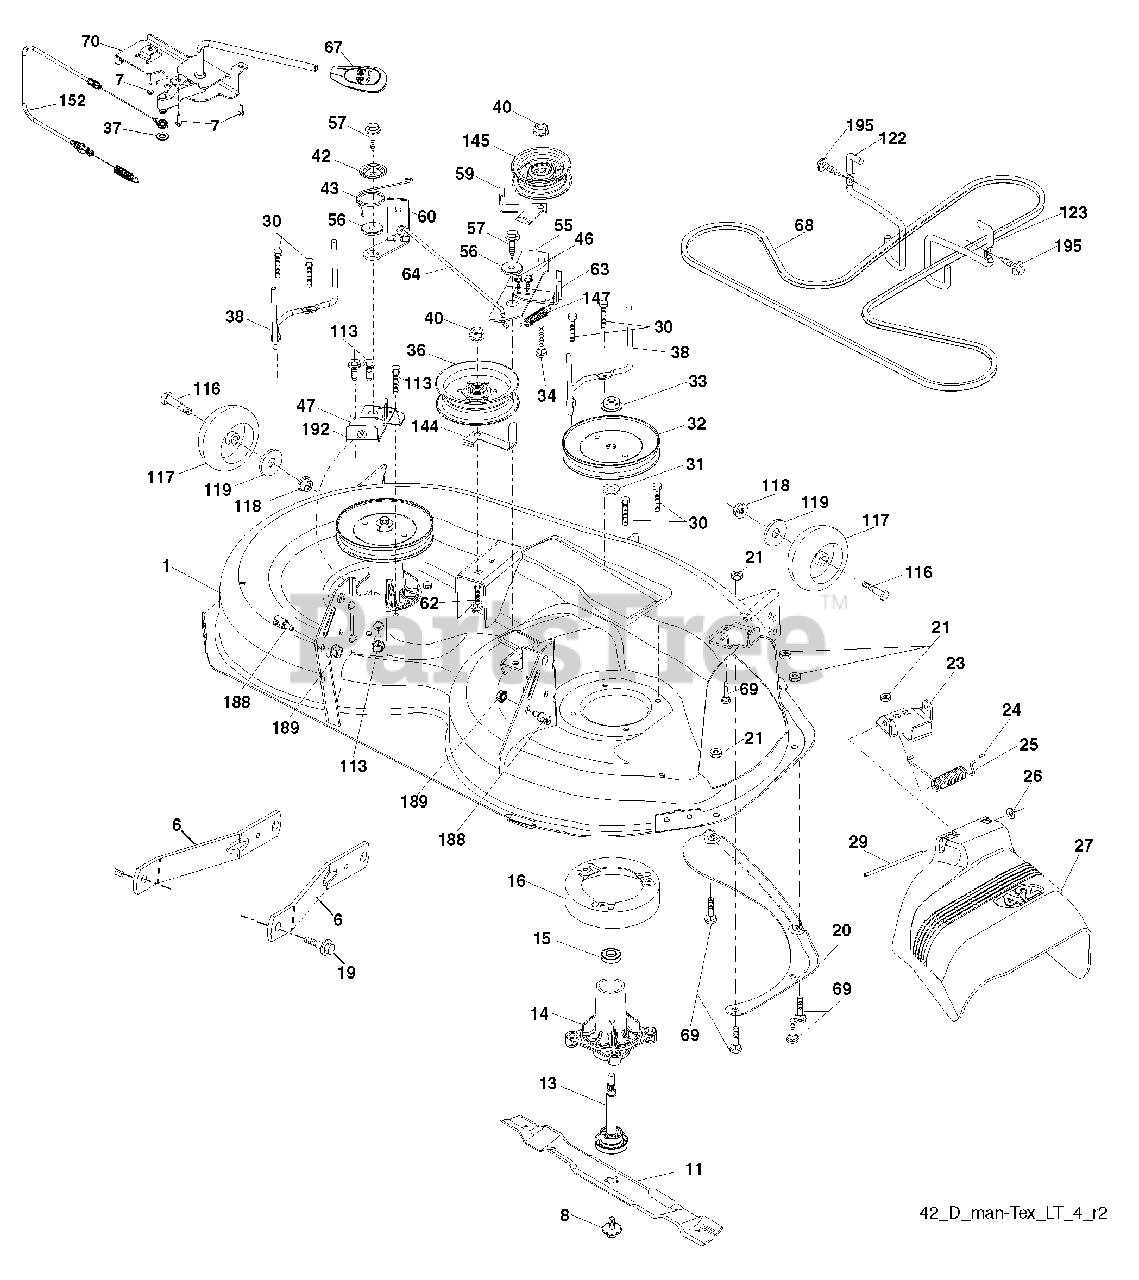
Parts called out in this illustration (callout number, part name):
1	Deck Weldment Mower
6	Arm Suspension
7	Screw 10 x 3/4 Single Lead
8	Bolt/Washer asm 7/16-20 unf
11	Blade, 42" Hi-Lift (For bagging or discharge)
13	Shaft Assembly, Mandrel
14	Housing, Mandrel
15	Bearing, Ball, Mandrel
16	Stripper, Mower Deck
19	Bolt, Shoulder
20	Baffle, Vortex
21	Nut, Crownlock 5/16-18 unc
23	Bracket, Deflector
24	Cap, Sleeve
25	Spring, Torsion, Deflector
26	Nut, Push
27	Shield, Deflector
29	Rod, Hinge
30	Screw Thdrol Rolling Wsh Hd
31	Washer, Spacer
32	Pulley, Mandrel
33	Nut, Toplock, Flanged
34	Bolt Carr Sh. 3/8-16 x 1-1/2 Gr. 5
36	Pulley, Idler, Flat
37	Washer
38	Keeper Belt LH Mandrel
40	Nut, Lock Flg. 3/8-16 unc
42	Spring Torsion Brake
43	Spring Torsion Retainer
46	Screw Thd Roll 1/4-20 x 5/8
47	Bracket Clutch Cable
55	Arm, Idler
56	Spacer, Retainer
57	Screw 3/8-16 x 1
59	Guard, Tuv Idler
60	Arm Brake Mower
62	Bolt Rd Hd Sq Nk 3/8-16 unc x 2
63	Arm Brake Mower
64	Link Brake Asm
65	Spacer Retainer
67	Handle Clutch Cable
68	V-Belt
69	Bolt
70	Clutch Asm Manual
88	Screw 10-24 x 5/8
113	Bolt 5/16-18
116	Bolt, Shoulder
117	Wheel, Gauge
118	Nut, Crownlock 3/8-1
119	Washer 13/32 x 7/8 x 14 Ga.
122	Keeper Belt Engine LH
123	Keeper Belt Engine RH
144	Keeper Belt
145	Pulley Idler
147	Spring Return
152	Manual Clutch Cable
188	Stud Fastener
189	Nut Lock Hex Flange
192	Bracket Brake Stand LH
195	Screw Hex Wsh THDR 3/8-16 x 3/4
195	Mandrel Assembly
195	Replacement Mower, Complete
